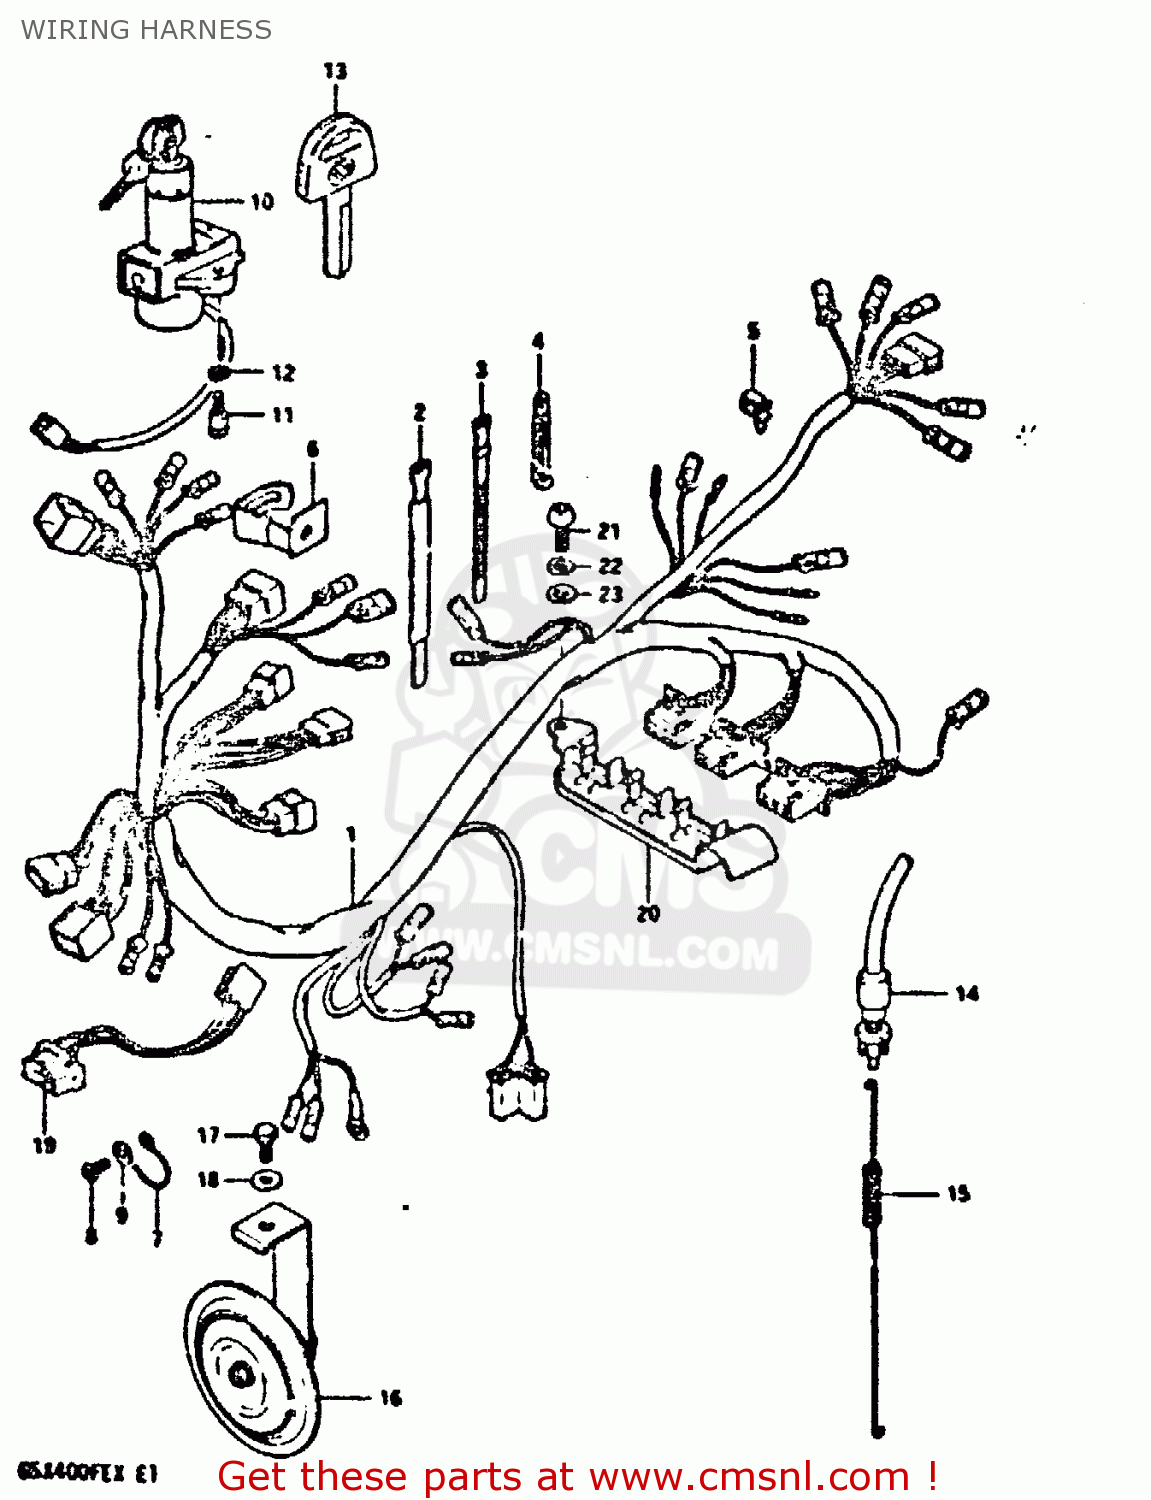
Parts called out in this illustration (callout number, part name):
1	WIRING HARNESS
2	CLAMP
3	CLAMP(L:80)
4	CLAMP
5	CLIP
6	CLAMP,WIRING HARNESS
7	GUIDE,WIRING HARNESS
8	SCREW 6X12
9	WASHER
10	SWITCH ASSY,IGNITION
11	BOLT
12	LOCK WASHER
13	KEY,BLANK
14	SWITCH ASSEMBLY,STOP LAMP
15	SPRING
16	HORN
17	BOLT 8X12
18	WASHER 6MM
19	LEAD WIRE,HEADLAMP
20	PLATE, COUPLER
21	BOLT
22	LOCK WASHER
23	WASHER
